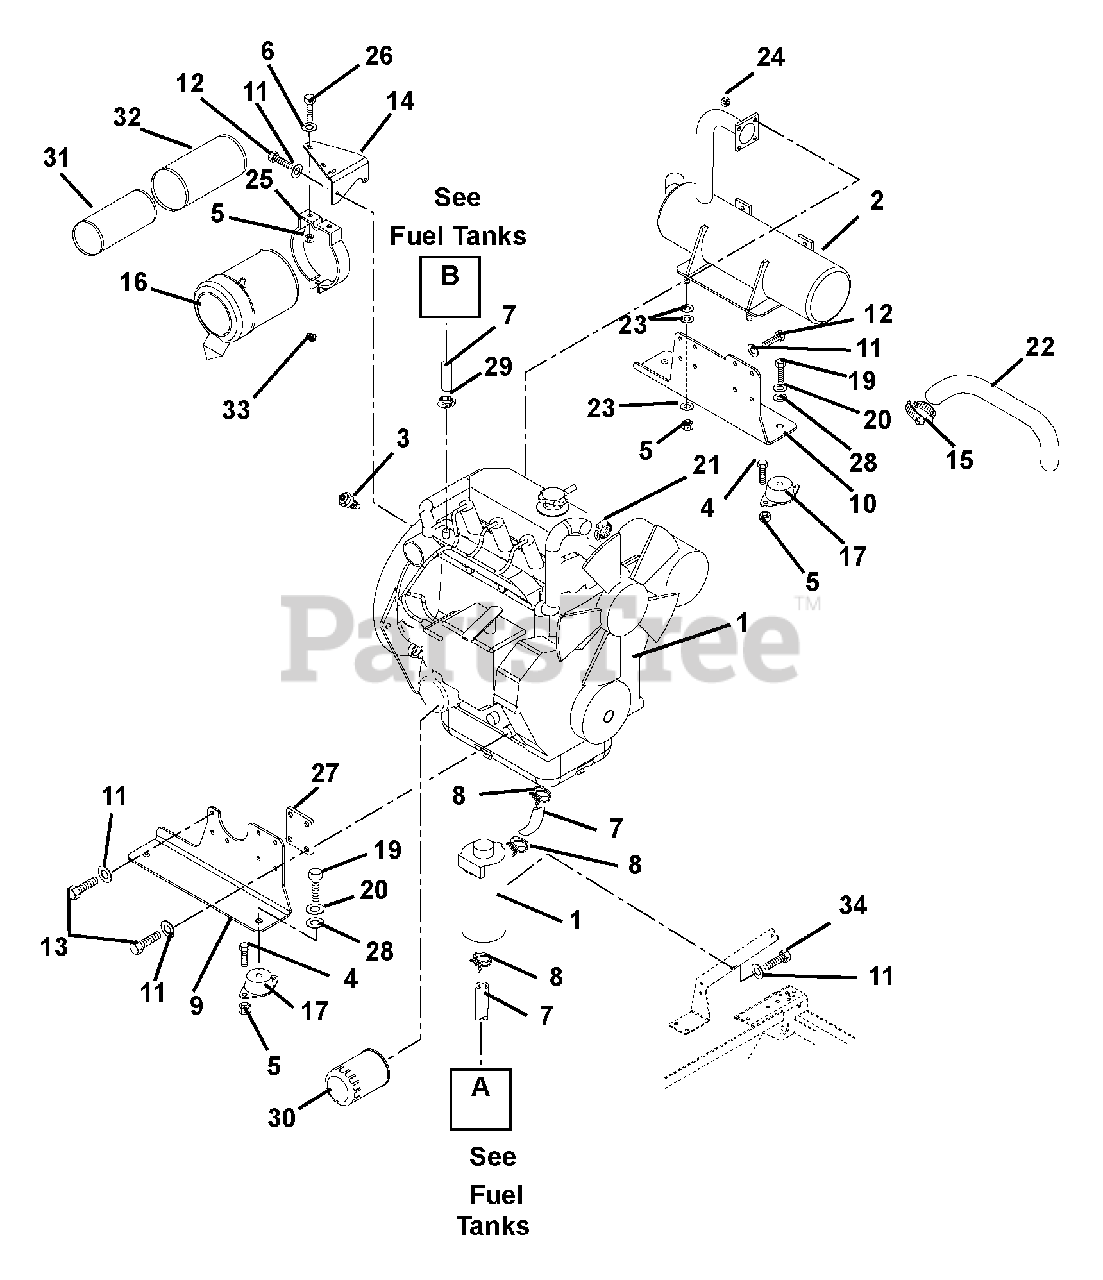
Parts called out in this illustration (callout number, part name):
1	Engine, 27HP Daihatsu Diesel (950D)
3	Sender, Temperature
4	Bolt, Hex .31-18 x .75 Grade 5
5	Nut, Locking Top Flange .31-18
6	Washer, Locking .25 x .062 Regular
7	Gas Line, Bulk .31" ID
8	Hose, Clamp
9	Mount, Engine Right Hand
10	Mount, Engine Left Hand
11	Washer, Lock .31 x .078 Regular
12	Bolt, Hex M8-1.25 x 20
13	Bolt, Hex M8 x 1.25 x 25 Grade 8
14	Bracket, Air Cleaner
15	Clamp, 2.50" Dia. Hose
16	Assembly, Air Cleaner
17	Mount, Engine
18	Bolt, Hex .31-18 x 1.00 Grade 5
19	Bolt, Hex .50-20 x 1.00 Grade 5
20	Washer, Locking .50 x .125 Regular
21	Clamp, Hose 1.50 x .81 x 1.42
22	Hose, Air Cleaner
23	Washer, Flat Steel .38 x .875 x .083
24	Nut, Locking, Top M8-1.25
25	Bracket, Air Cleaner Mount
26	Washer, Flat Steel .38 x .875 x .083
27	Spacer, Engine Mounting
28	Washer, Flat Steel .531 x 1.06 x .095
29	Hose Clamp
30	Oil Filter
31	Element, Inner Safety
32	Element, Outer Primary
33	Plug, Pipe .125-27
34	Bolt, Hex M6-1 x 16
